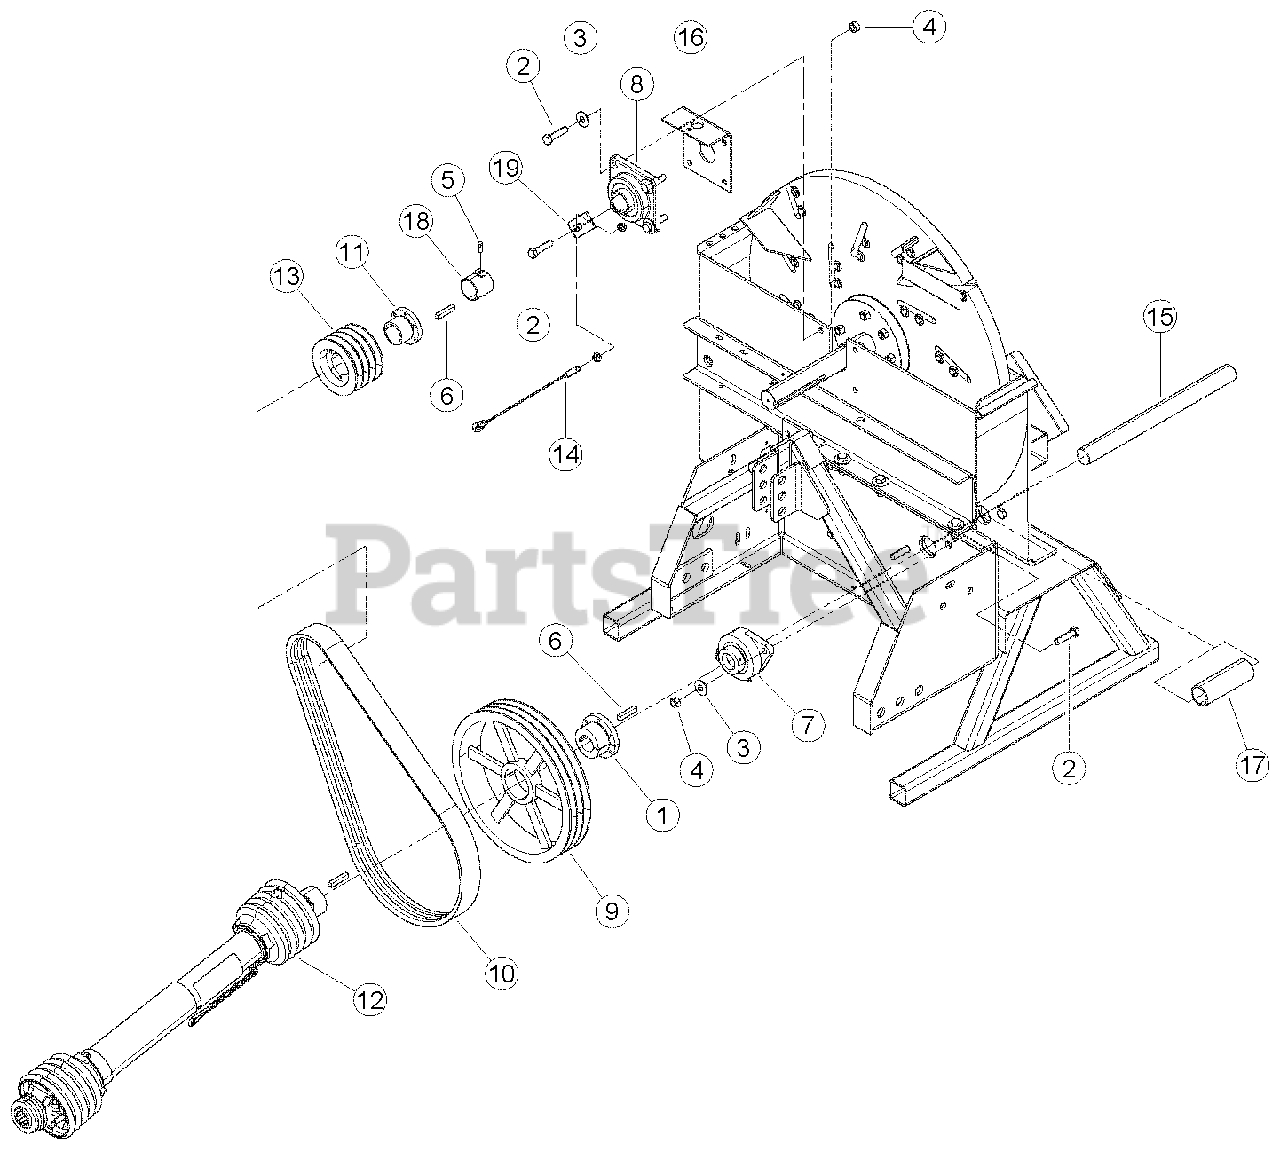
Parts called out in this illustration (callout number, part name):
1	BUSHING, SK 1-1/2"
2	BOLT, 1/2 X 2 HEX HD GR5 ZP
3	WASHER, 1/2 FLAT ZP
4	NUT, 1/2 CENTERLOCK GRB ZP
5	SCREW, 5/16-18 X 5/8 SQ HD SET
6	KEY, 3/8 SQUARE X 2 LONG PLAIN
7	BEARING, 2 BOLT FLANGE 1-1/2" BORE
8	BEARING, 4 BOLT FLANGE 1-3/4" BORE
9	SHEAVE, 3B13.6 SK
10	BELT, 3RB64
11	BUSHING, SD 1-3/4"
12	DRIVESHAFT. (WAS PN 16958, REPLACED AND SUPERSEDED. FOR SERVICE ORDER PN 32219-00 DRIVELINE)
12	DRIVELINE
13	SHEAVE, 4BQ4.8 SD
14	SENSOR, PROXIMITY
15	JACKSHAFT, CHIPPER DRIVE
16	WELDMENT, LEFT BEARING BRACKET
17	SHIELD, SHAFT
18	WELDMENT, SPACER
19	BRACKET, SENSOR SHORT MOUNT
